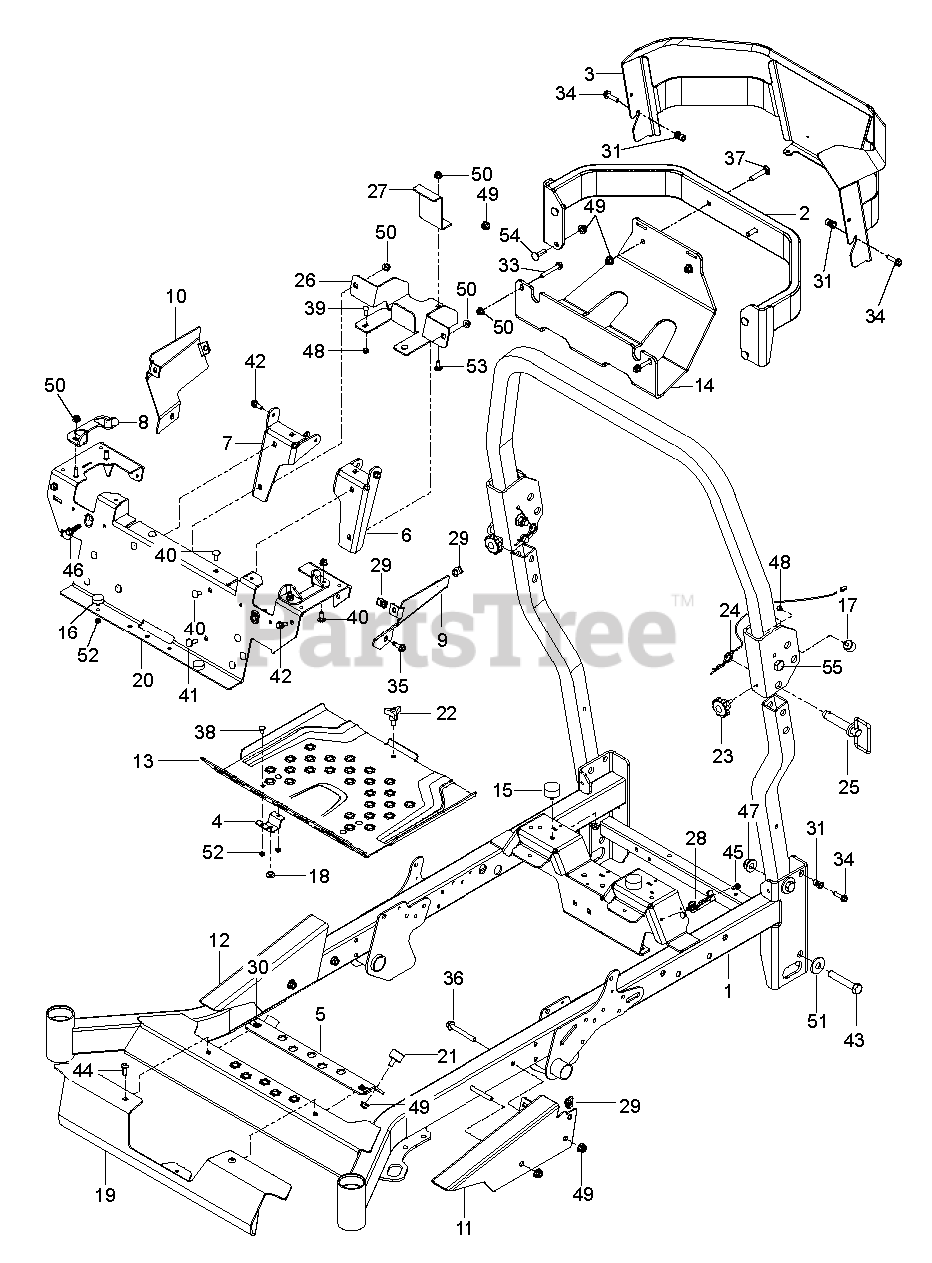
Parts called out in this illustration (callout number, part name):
1	FRAME.W/DECALS.48-60".ORG
2	BUMPER.REAR.ORANGE
3	GUARD.PNT.ENGINE.GREY
4	COVER.PNT.VALANCE.PZ.GREY
5	BRACKET.PNT.ISOLATOR.SUPPT.BLK
6	BRACKET.PNT.MTG.SEAT.LH.EDIP
7	BRACKET.PNT.MTG.SEAT.RH.EDIP
8	CABLE.YOKE.PARK.BRAKE
9	PANEL CLOSE OUT LH ORANGE MS-6
10	PANEL CLOSE OUT RH ORANGE MS-6
11	PANEL.PNT.WEDGE.LH.ORG
12	PANEL.PNT.WEDGE.RH.ORG
13	PLATE.PNT.FOOTREST.PZ.ORANGE
14	PLATE SKID, Z500 LONG YAMAHA G
15	BUMPER 5/16-18
16	BUMPER, 1/4-20 STUD, 1/4
17	BUMPER, MALE STUD, 1/4-20
18	GROMMET, BUMPER
19	COVER.PNT.VALANCE.PZ.GREY
20	CROSS.MEMBER.PNT.SEAT.FRONT.OR
21	ISOLATOR.PZ.FOOTREST
22	KNOB W/STUD
23	KNOB.5/16-18X1"BLACK
24	PIN.HAIR.DOUBLE.LOOP.W/LANYARD
25	PIN.ROPS.W/HANDLE
26	PLATE.PNT.BATTERY.EDIP
27	BRACKET.PNT.MOUNT.BATTERY.EDIP
28	BRACKET.FUSE.RELAY.HOUSING.PZ
29	U-CLIP 5/16-18 NUT RETAINER
30	SCREW.BUTTON.HEAD.TORX.3/8-161
31	NUTSERT 5/16-18 THICK GRIP
33	HHFS 5/16-18 X 2.25 GD 5
34	HHFS 5/16-18 X 1.25 TPBLT GD 5
35	SCREW
36	HHFS 3/8-16 X 3 GRD 5 ZD
37	RHSNB 3/8C X 2
39	1/4-20X3/4 CARR BLT
40	BOLT 5/16C X 3/4" CARRIAGE
41	RHSNB 5/16C X 1
42	BOLT, SHOULDER
43	5/8-11 X 3-1/2 HHB GRADE 5
44	SCREW.BUTTON.HEAD.TORX.3/8-161
45	SCREW
46	SCREW.SHAKEPROOF.1.25.BLACK
47	NUT 5/8-11 FLG NYLOC ZD
48	NUT.1/4-20.HEX.NYLOC.ZD
49	NUT 3/8-16 HEX FLG NYLOC ZD
50	5/16-18 NYLOC FLANGE NUT
51	WASHER, 5/8 FLAT
52	JAM NUT 1/4C (2 2 PW01)
53	SCREW M6 X 8MM HEX CAP
54	BOLT.3/8-14X1.25
55	BOLT.HEXAG.5/8-11X4-1/4.G5.ZPY
